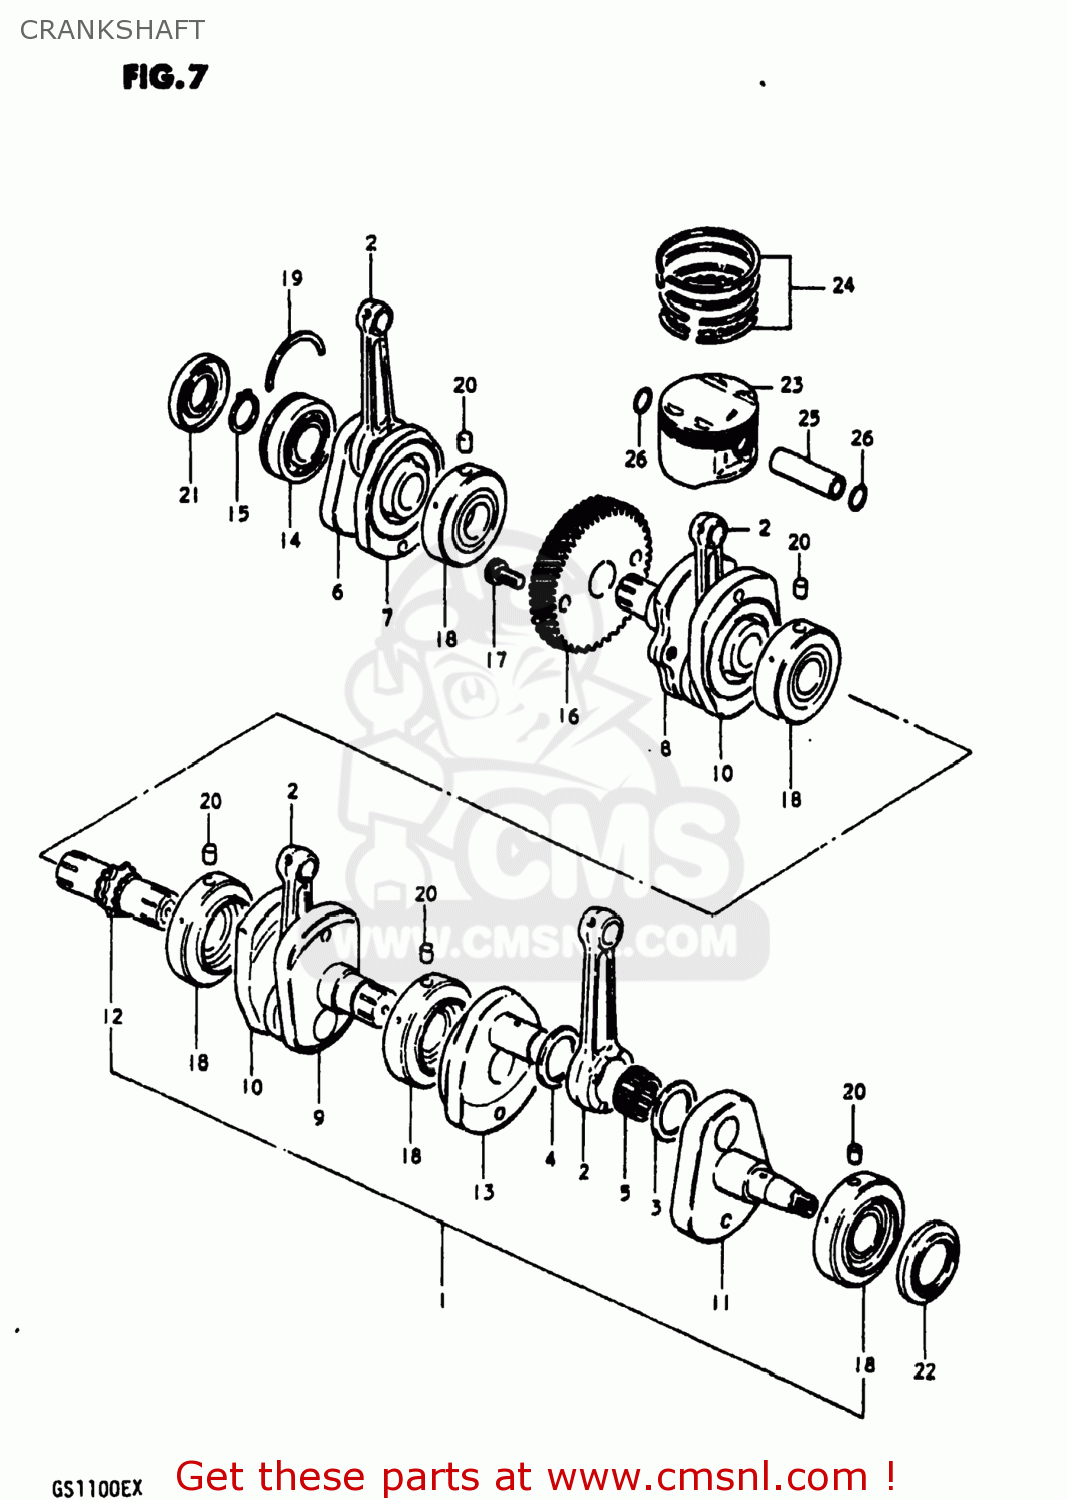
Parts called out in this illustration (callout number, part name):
1	CRANKSHAFT ASSEMBLY
2	CONNECTING ROD
3	WASHER(31X48.5X1)
4	WASHER(31X48.5X2)
5	BEARING(31X39X21)
6	CRANKSHAFT,RIGHT
7	WEB,CRANK
8	CRANKSHAFT
9	CRANKSHAFT,MIDDLE,LEFT
10	WEB,CRANK,MIDDLE
11	CRANKSHAFT,LEFT
12	SHAFT,TIMING CHAIN DRIVE
13	WEB,CRANK,LEFT
14	BEARING(30X72X19)
15	CIRCLIP,30MM
16	GEAR,PRIMARY DRIVE
17	BOLT
18	BEARING
19	C RING
20	PIN
21	SEAL,OIL(30X72X11)
22	SEAL,OIL(47.3X60X6.5)
23	PISTON
24	RING SET,PISTON
25	PIN,PISTON
26	CIRCLIP
